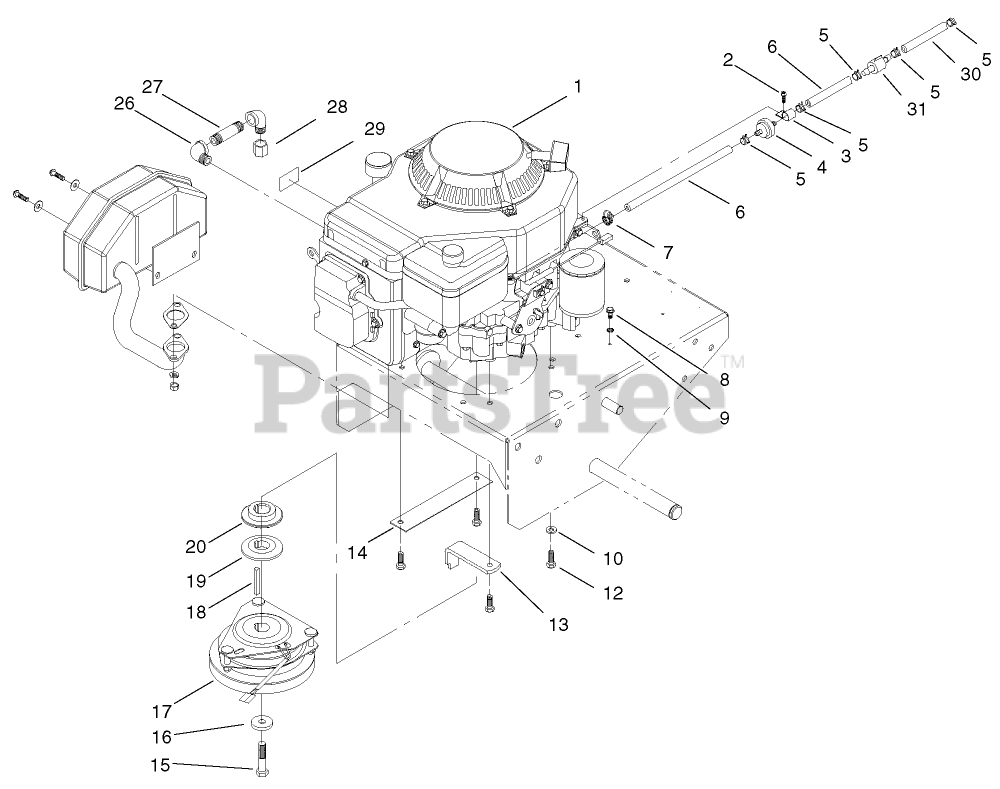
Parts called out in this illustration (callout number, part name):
2	SCREW-SHWH
3	CLAMP-CABLE
4	FILTER-FUEL
5	CLAMP-HOSE
7	CLAMP-WORM
8	SCREW
9	WASHER-LOCK/EXT
10	WASHER-PLAIN
12	SCREW-HH
13	RETAINER-CLUTCH
14	GUARD-PULLEY
15	SCREW-HH
16	WASHER
17	CLUTCH/BRAKE
18	KEY-SQUARE
19	SHEAVE-LOWER HALF
20	SHEAVE-UPPER HALF
26	ELBOW-STREET, 90 DEG
27	NIPPLE-PIPE
28	CAP-PIPE
29	DECAL-SURFACE, HOT
31	VALVE-FUEL
